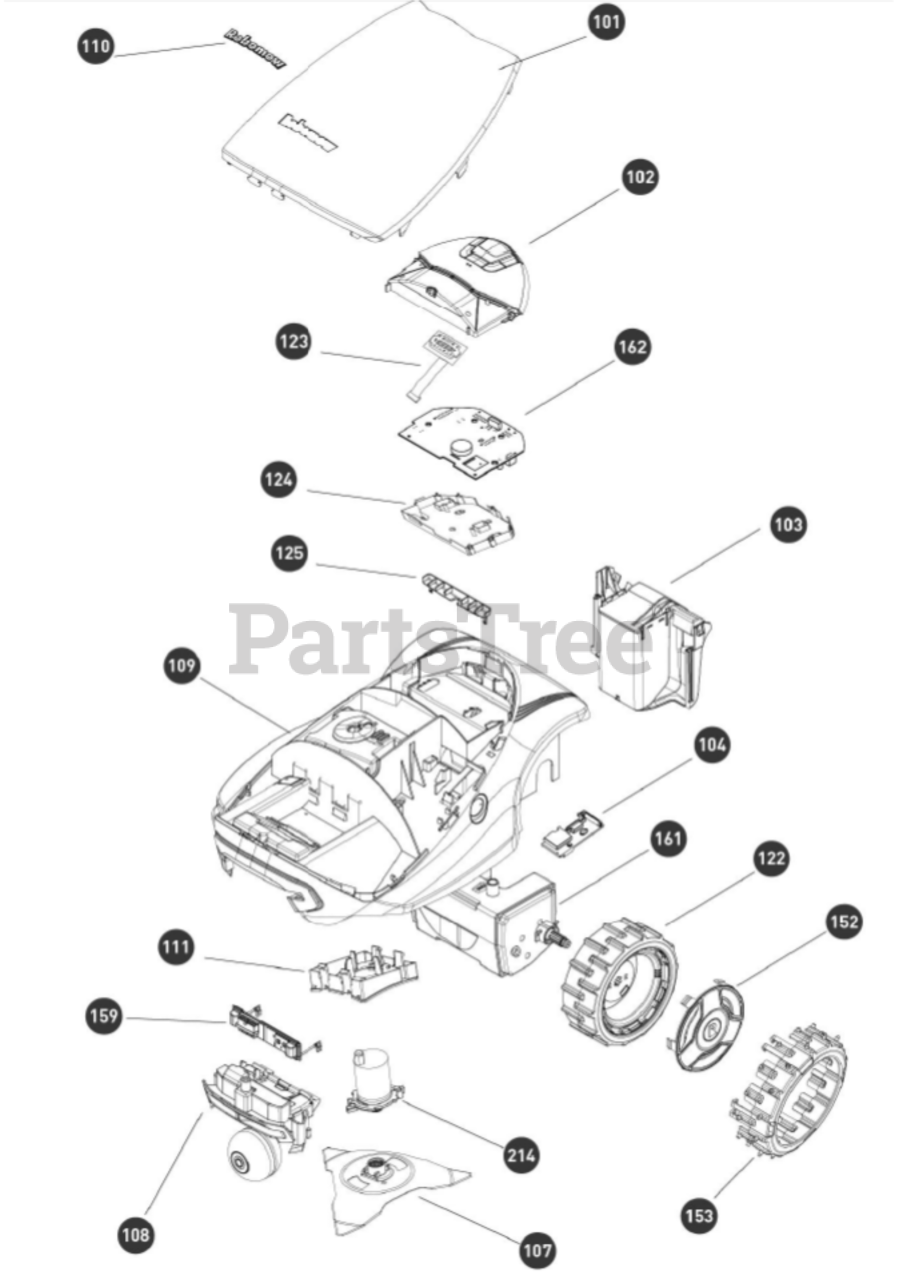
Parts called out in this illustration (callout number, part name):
101	C COVER ASSEMBLY (GREEN)
102	RC PANEL ASSEMBLY W/O LCD DISPLAY
103	BATTERY (RC/TC/MC)
104	GSM W/GPS US (CATM1)
107	HIGH CUT BLADE KIT
108	NOZZLE ASSEMBLY
109	RC CHASSIS ASSEMBLY (BRUSH)
110	ROBOMOW STICKER C MODELS
111	MOWING DECK FLANGE
122	POWER WHEELS (RC MODEL - PAIR)
123	RC LCD ASSEMBLY
124	Main Circuit Board Protector RC
125	RC DRAIN PROTECTOR
152	RC PREMIUM TAS
153	ROBO GRIPS FOR RC
159	RC FRONT BOARD
161	GEAR CASE ASSY HD (SPARE PARTS)
162	MAIN ELECTRICAL BOARD
214	MOWING MOTOR ASSEMBLY (BRUSH)
